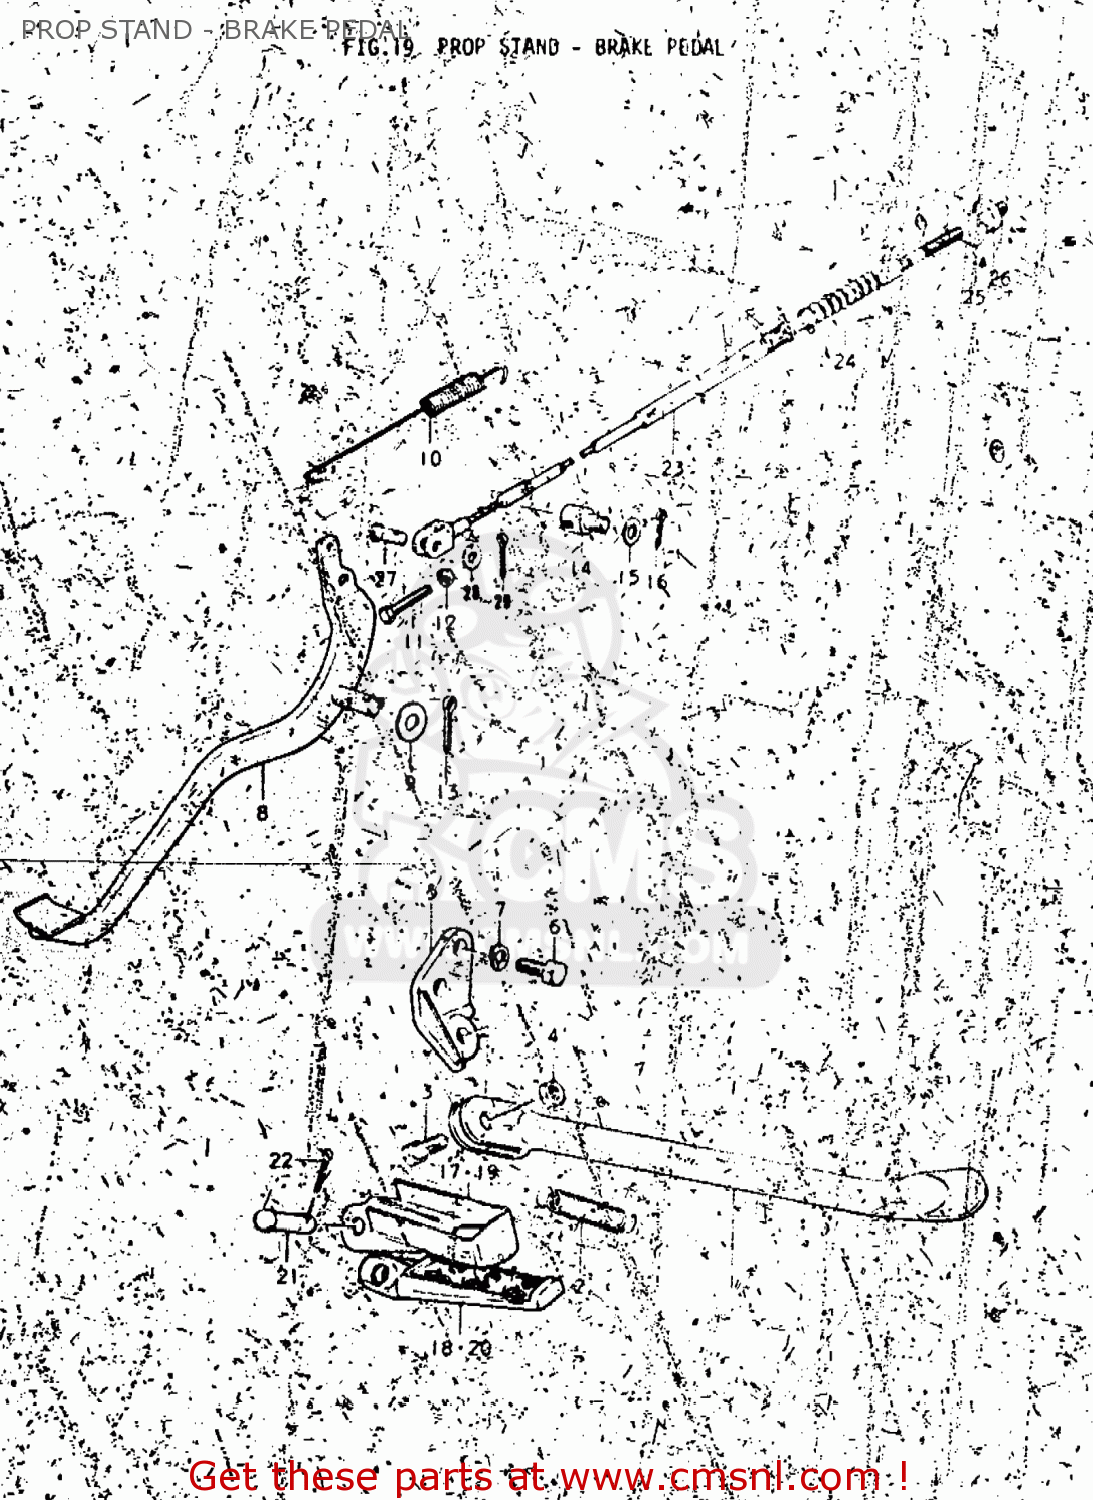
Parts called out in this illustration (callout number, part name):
1	STAND,SIDE
2	SPRING
3	BOLT(10X30)
4	NUT
5	BRACKET,SIDE STAND
6	BOLT
7	LOCK WASHER
8	PEDAL,BRAKE
9	WASHER
10	SPRING
11	BOLT
12	NUT
13	PIN 30X20
14	PROP STAND
15	WASHER
16	PIN 25X20
17	FOOTREST,FRONT,RIGHT
18	BAR,FRONT FOOTREST
19	FOOTREST,FRONT,LEFT
20	BAR,FOOTREST,LEFT
21	PIN
22	PIN
23	CABLE,RR BRAKE
24	SEAL,DUST
25	PIN
26	NUT
27	PIN(L:13.5)
28	WASHER
29	PIN
